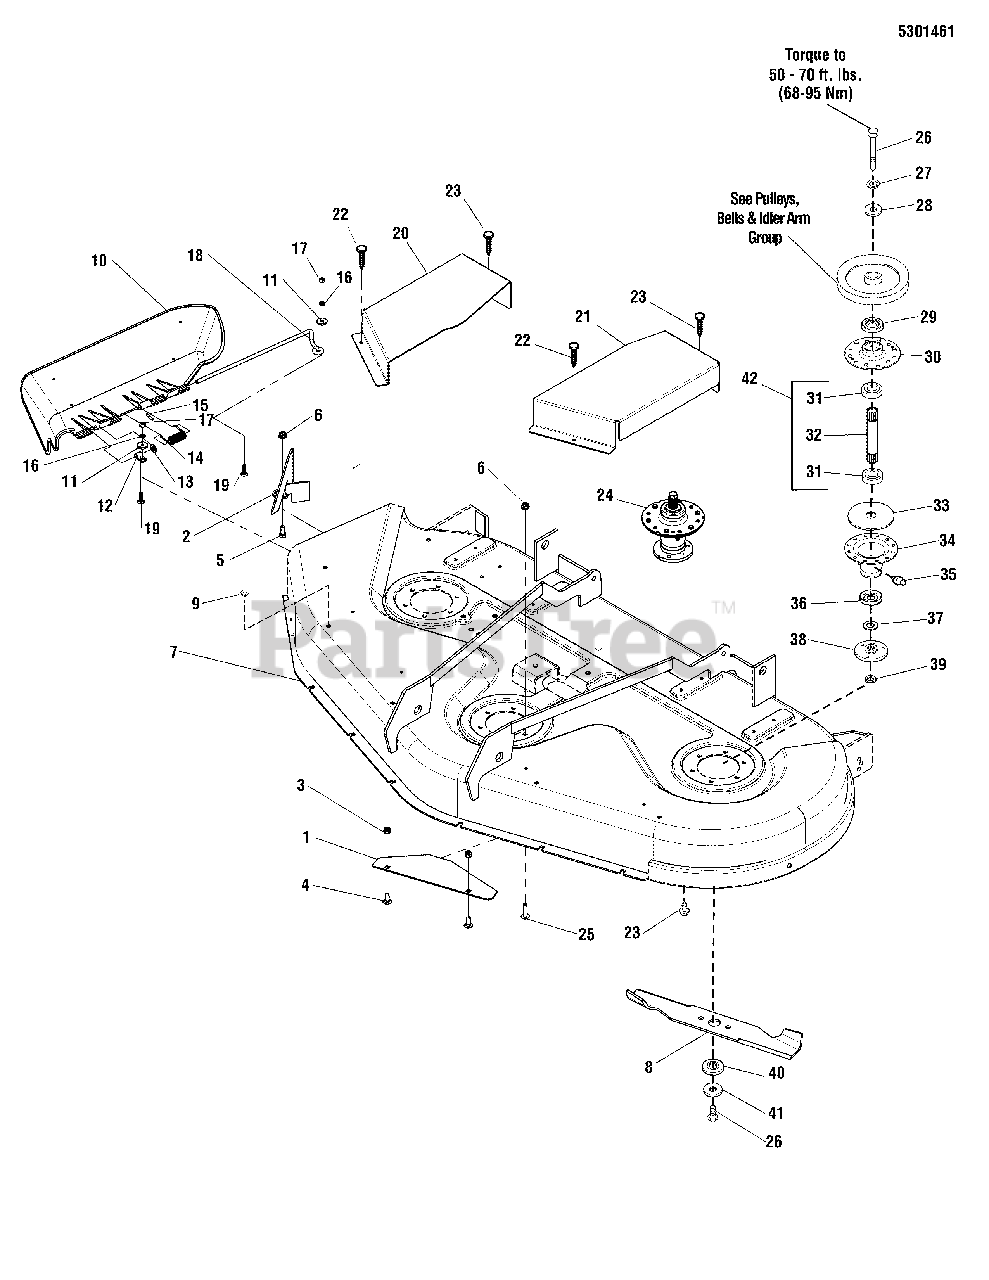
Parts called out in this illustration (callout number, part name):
1	BAFFLE, FRONT BLO-BLACK
2	BAFFLE, DISCHARGE 10GA 54" MWR-BLACK
3	NUT, 5/16-18 HEX NYLOCK FLANGE
4	BOLT, RD HD SH SQ NK 5/16-18X0.750 G5 BLK
5	BOLT, 5/16-18 X 3/4 GD5
6	NUT, 5/16-18 HEX NYLON LOCK
7	DECK SHELL W/DECALS, 54, SNP2654 DLR
8	KIT, 54" MOWER BLADES (1736043 - 2; 1736044 - 1)
9	PLUG, BUTTON FOR 0.344SQ HOLE BLACK POLY
10	DEFLECTOR, BLACK
11	WASHER, 0.250(0.26IDX0.84ODX.12THK) BLK
12	CLAMP, WIRE, .312DIA . (1) .281 HOLE BLK
13	WASHER, 0.312 (0.34IDX0.75ODX.06THK) BLK
14	SPRING, TORSION CHUTE 44/50" BLK
15	CAP, VINYL
16	LOCKWASHER, SPRING .250 BLK
17	NUT, 1/4-20 HEX
18	ROD, DEFLECTOR
19	BOLT, RD HD SH SQ NK 1/4-20X0.875 G5 BLK
20	PLATE, GUARD, MOWER DECK, 54", RH - RED
21	PLATE, GUARD, MOWER DECK, 54", LH - RED
22	CAPSCREW, Hex Washer Head Taptite, 1/4-20X0.375 .56
23	CAPSCREW, Hex Washer Head Taptite, 5/16-18X0.750BLK
24	SPINDLE ASSM, - STAMP STEEL LG SHAFT
25	BOLT, 5/16-18 X 1 1/4 FLANGE
26	CAPSCREW, HEX HEAD 7/16-14x1-1/4 G8 YELLO (SV)
27	LOCKWSHER, SPRING .438 BLK (SV)
28	WASHER, 0.438(0.45IDX1.25ODX.25THK) BLK (SV)
29	SHIELD, BEARING,MOWER ARBOR UPPER HT TR (SV)
30	HOUSING, ARBOR TOP - BLACK (SV)
31	BEARING, BALL 0.750ID 1.780OD 0.610LG (SV)
32	SHAFT, ARBOR 1.000DIA (SV)
33	GASKET, FOAM POLY (SV)
34	HOUSING & FITTING ASMY-LOWER BLACK (SV)
35	FITTING, LUBE .250 DRIVE .25SH BL CHK YEL (SV)
36	SHIELD, BEARING, MOWER ARBOR LOWER HT TR (SV)
37	WASHER, SHIM, .75 0.7535IDX1.388ODX0.30T (SV)
38	ADAPTER, BLADE 3.375OD INT SPLINE PWD MTL (SV)
39	RETAINING RING, EXT, #75 0.750 SELF LOCK (SV)
40	WASHER, Spacer, SPLN.6134IDX2.00OD.390TH SINTERPS (SV)
41	WASHER, Splined, 2" OD, .187" Thick (SV)
42	SHAFT & BEARING ASSM. (SV)
